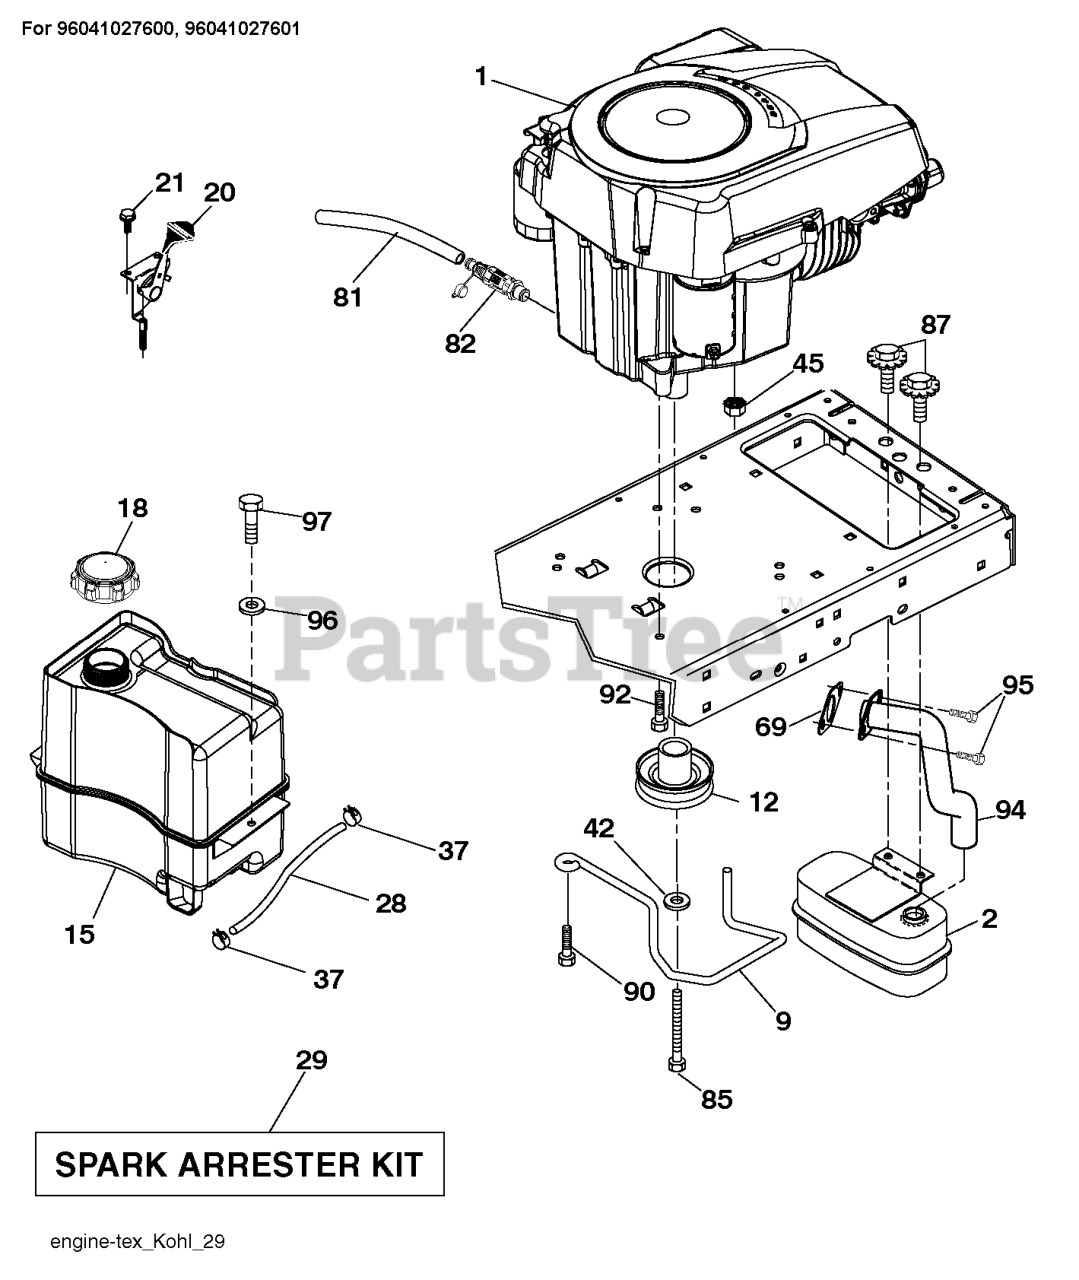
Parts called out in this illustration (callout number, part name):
2	MUFFLER.SINGLE.CYL.KOHL/B&S
2	MUFFLER.ASM.SINGLE
9	KEEPER.BELT.ENGINE.4.2
12	PULLY ENGINE
15	TANK.ASSEMBL.2.5GAL.NON-EPA
18	FUEL CAP
18	CAP ASM.FUEL.2.25"FR.
20	CONTROL.TH/CK.COBRA.KO
21	SCREW.#10 X 0.750.BOS
28	LINE.FUEL.20"FRONT.EMI
29	KIT.SPARK ARRESTOR 794945 B&S
37	HOSE CLAMP
42	LOCKWASHER
45	NUT
69	GASKET.EXHAUST.KOHLER
81	TUBE, DRAIN OIL ASM.
82	VALUE.OIL.DRAIN
85	BOLT HEX 7/16-20X4-1/4"
87	BOLT 5/1618UNC X 3/4 W/ SEMS
90	SCREW 3/8-16X1
92	SCREW 3/8-16X1
94	RP.TUBE.EXHAUST.KOHL.COURAGE
95	SCREW.SOCKET HD.5/16-1
97	SCREW HEXWSHR 1/4-20X3/4
